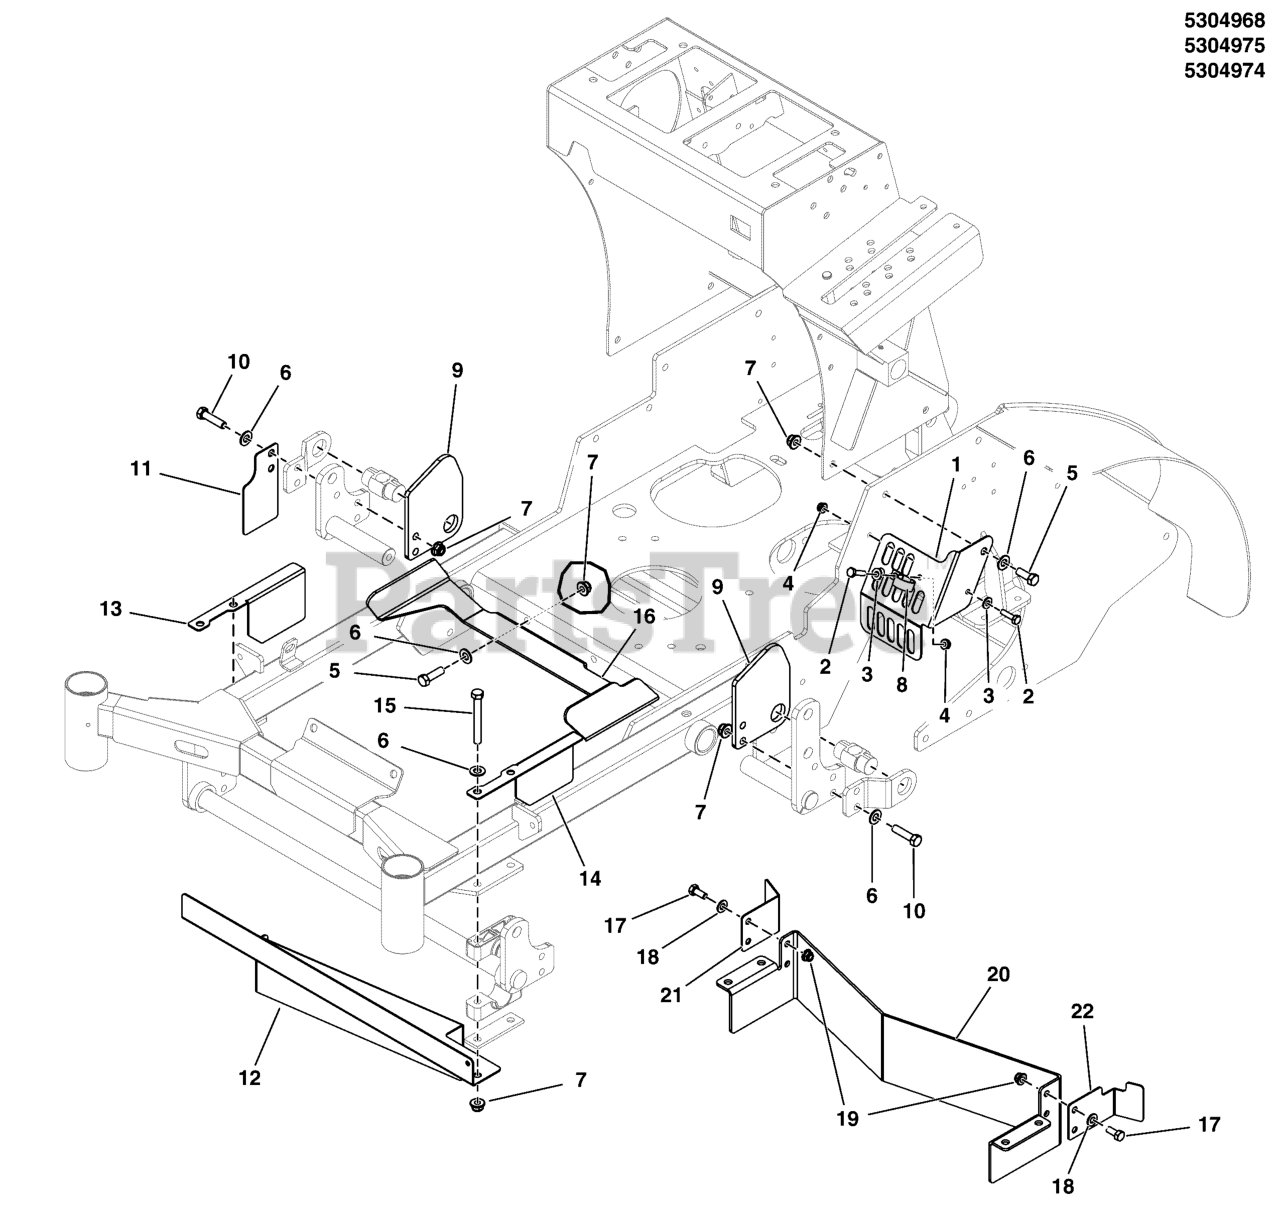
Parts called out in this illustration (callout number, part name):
1	PLATE, FAN GUARD, SRSZ1 CE - RED
2	BOLT, 1/4-20 X 3/4 GD5 CZ
3	WASHER, 1/4 SAE
4	NUT, 1/4-20 HEX NYLOCK FLANGE
5	BOLT, 3/8-16 X 1-1/4" GD5 CZ
6	WASHER, 3/8 SAE
7	NUT, 3/8-16 HEX NYLOCK FLANGE
8	CLAMP, VINYL INSULATED, 1.00
9	BRACKET, INNER TRUNION, CE - BLK
10	BOLT, 3/8-16 X 1-1/2" GD5 CZ
11	PLATE, PIVOT GUARD, 36 CE - BLK
12	PLATE, DECK GUARD, UPPER 36 CE - RED
13	PLATE, FRAME GUARD, RH - RED
14	PLATE, FRAME GUARD, LH - RED
15	BOLT, 3/8-16 X 3" GD5 CZ
16	PLATE, ENGINE GUARD, SRSZ1 CE - RED
17	BOLT, 5/16-18 X 3/4 GD5
18	WASHER, 5/16" SAE
19	NUT, 5/16-18 HEX NYLOCK FLANGE
20	PLATE, DECK GUARD, UPPER, 48 CE - RED
21	PLATE, FRAME GUARD, LOWER, RH - RED
22	PLATE, FRAME GUARD, LOWER, LH - RED
